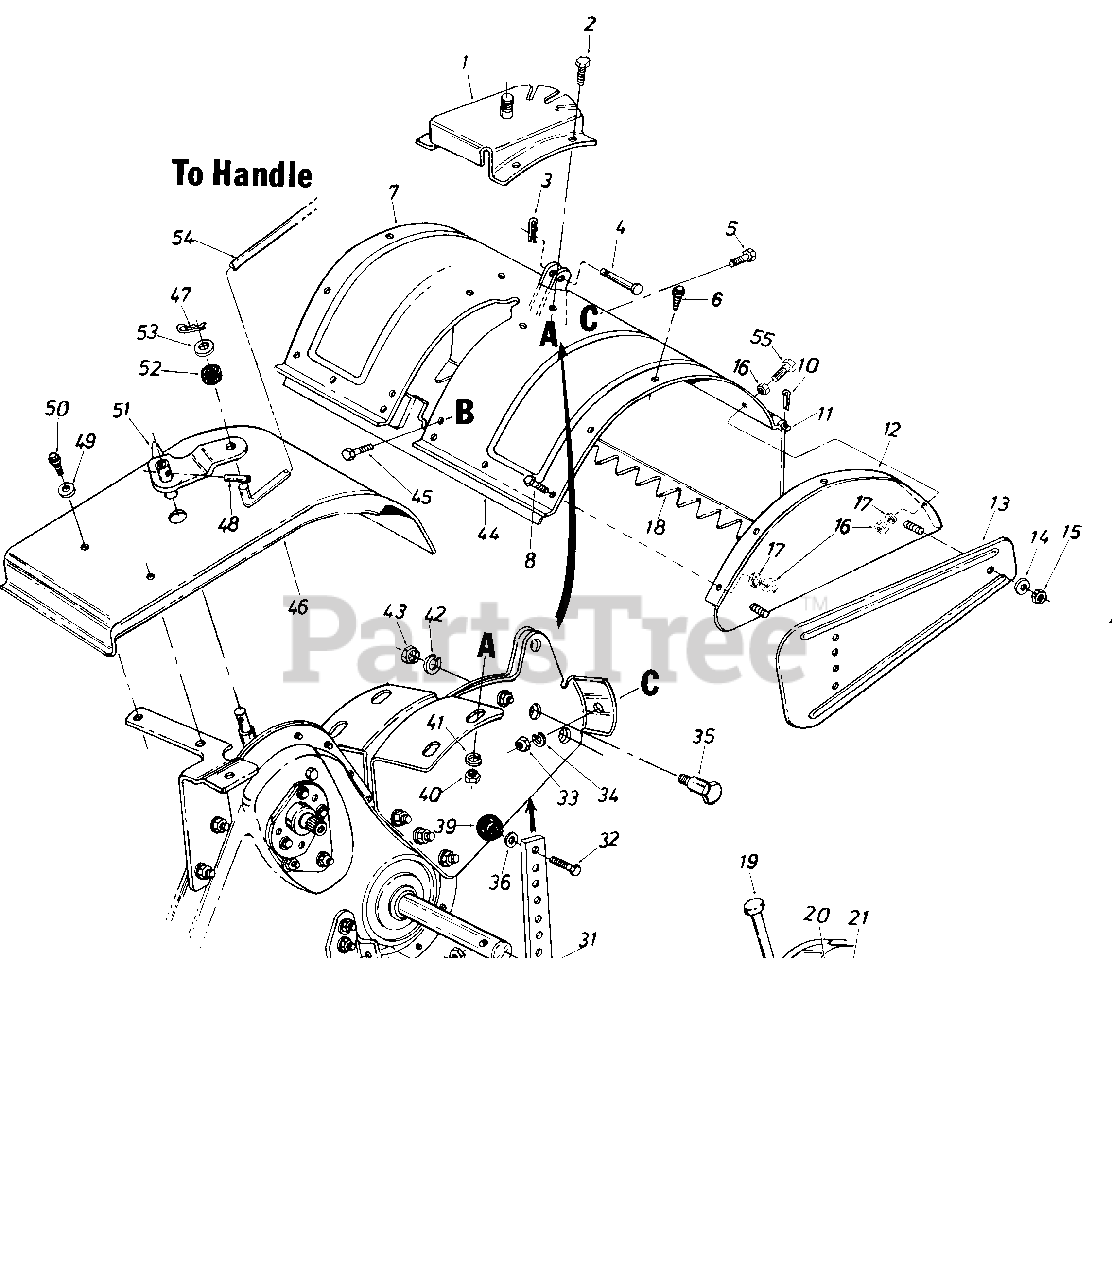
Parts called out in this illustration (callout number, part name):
1	Handle Positioner Brkt. Ass'y.
2	Hex Bolt 3/8-16 x .75" Lg.
3	Intern. Cotter Pin 5/16" Dia.
4	Clevis Pin .375" Dia.
5	Hex Bolt 5/16-18 x .75" Lg.
6	Hex Wash. Tap Scr.
10	Cotter Pin 3/32" Dia. x .75"
11	Tiller Flap Rod
15	Hex Nut 5/16-18 Thd.
16	Hex Nut 5/16-18 Thd.
17	L-Wash. 5/16" I.D.
19	Clevis Pin .375" Dia.
20	Hex Nut 3/8-24 Thd.
21	L-Wash. 3/8" I.D. H.D.
23	Shld. Bolt 1/2" Dia. x .175
24	Fl-Wash. .51" I.D. x 1.50"
25	Bell-Wash. .515" I.D. x 1.14"
26	Shld. Bolt 1/2" Dia. x .320
27	Intern. Cotter Pin
32	Hex Bolt 3/8-16 x .75" Lg.
33	Hex Nut 5/16-18 Thd.
34	L-Wash. 5/16" I.D.
35	Shld. Bolt 1/2" I.D. x .62" Lg.
36	Fl-Wash. 3/8" I.D. x 5/8" O.D.
37	Hex Nut 5/16-18 Thd.
38	L-Wash. 5/16" I.D.
39	Ball Knob
40	Hex Nut 3/8-16 Thd.
41	L-Wash. 3/8" I.D.
42	L-Wash. 3/8" I.D.
43	Hex Nut 3/8-16 Thd.
45	Hex Bolt 5/16-18 x .75" Lg.
46	Shift Cover
47	Intern. Cotter Pin 5/16" Dia.
48	Spring Roll Pin 3/16" Dia. x 1.00" Lg.
49	Fl-Wash. .281" I.D. x .62"
50	Hex Wash. Self-Tap Scr. 1/4-20 x .50" Lg.
51	Shifting Crank Ass'y. D x 2.05
52	Rubber Washer
53	Fl-Wash. .400" I.D. x 1.250"
54	Control Rod 37" Lg.
55	Hex Bolt 5/16-18 x 1-1/4" Lg.
